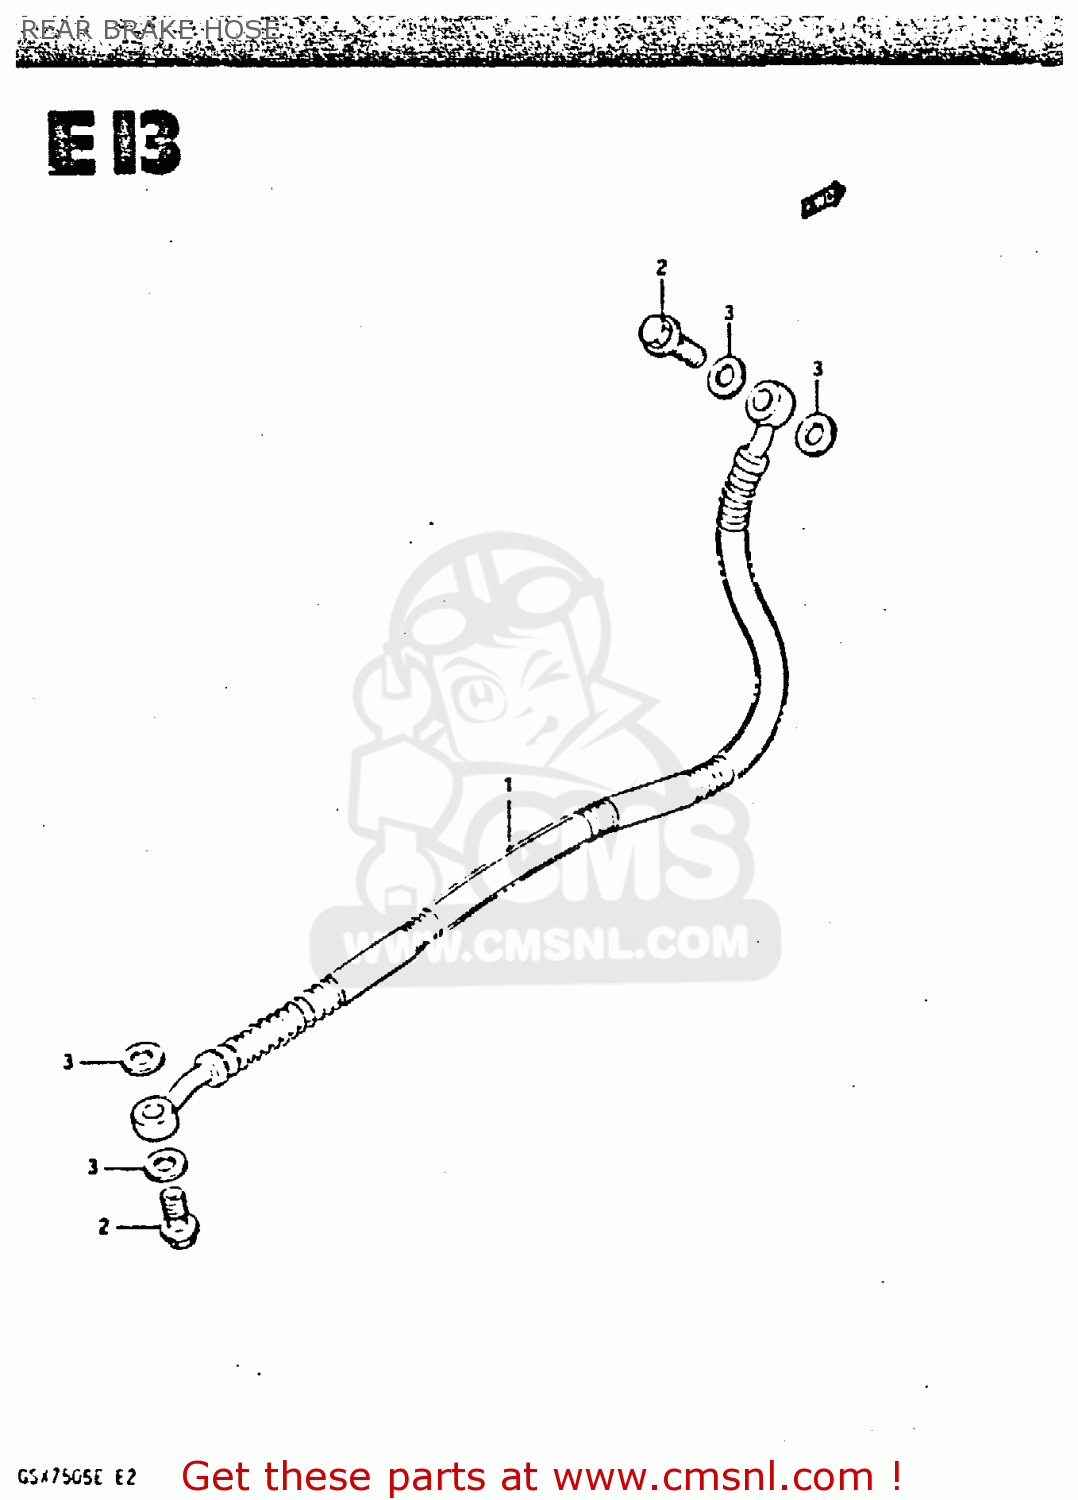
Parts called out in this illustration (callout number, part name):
1	HOSE, REAR BRAKE
2	BOLT UNION
3	WASHER(10X15X1.5)
